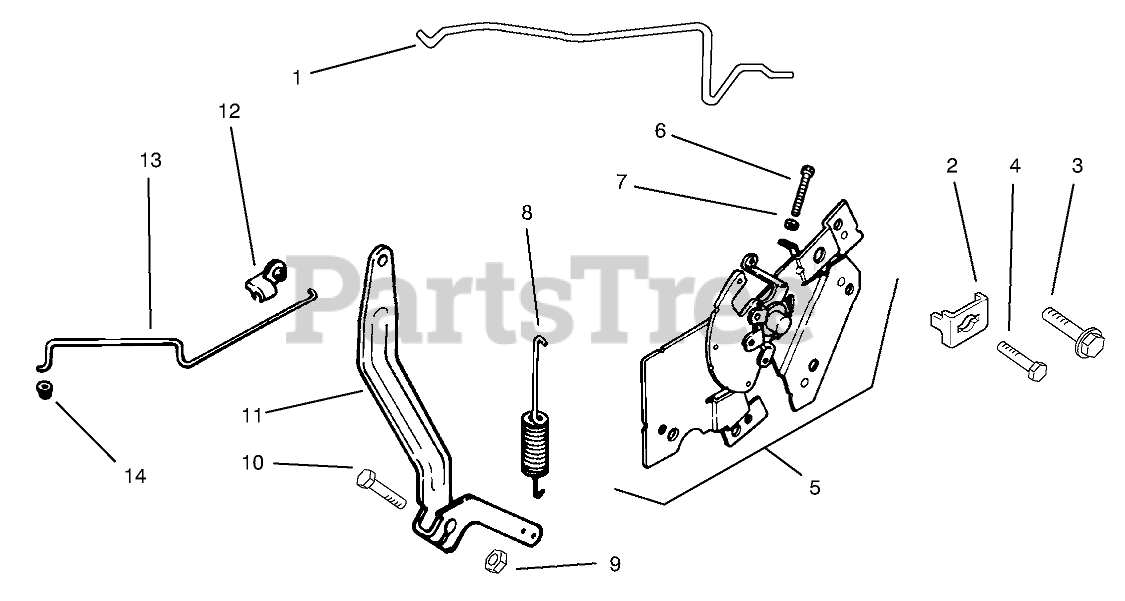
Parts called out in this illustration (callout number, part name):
1	Linkage Choke
2	Clamp
3	Screw Socket
4	Screw-HF
5	Control-Speed ASM
6	Screw
7	Nut
8	Spring-Governor
9	Nut
10	Screw
11	Lever-Governor
12	Bushing-Linkage
13	Linkage-Throttle
14	Bushing-Linkage
